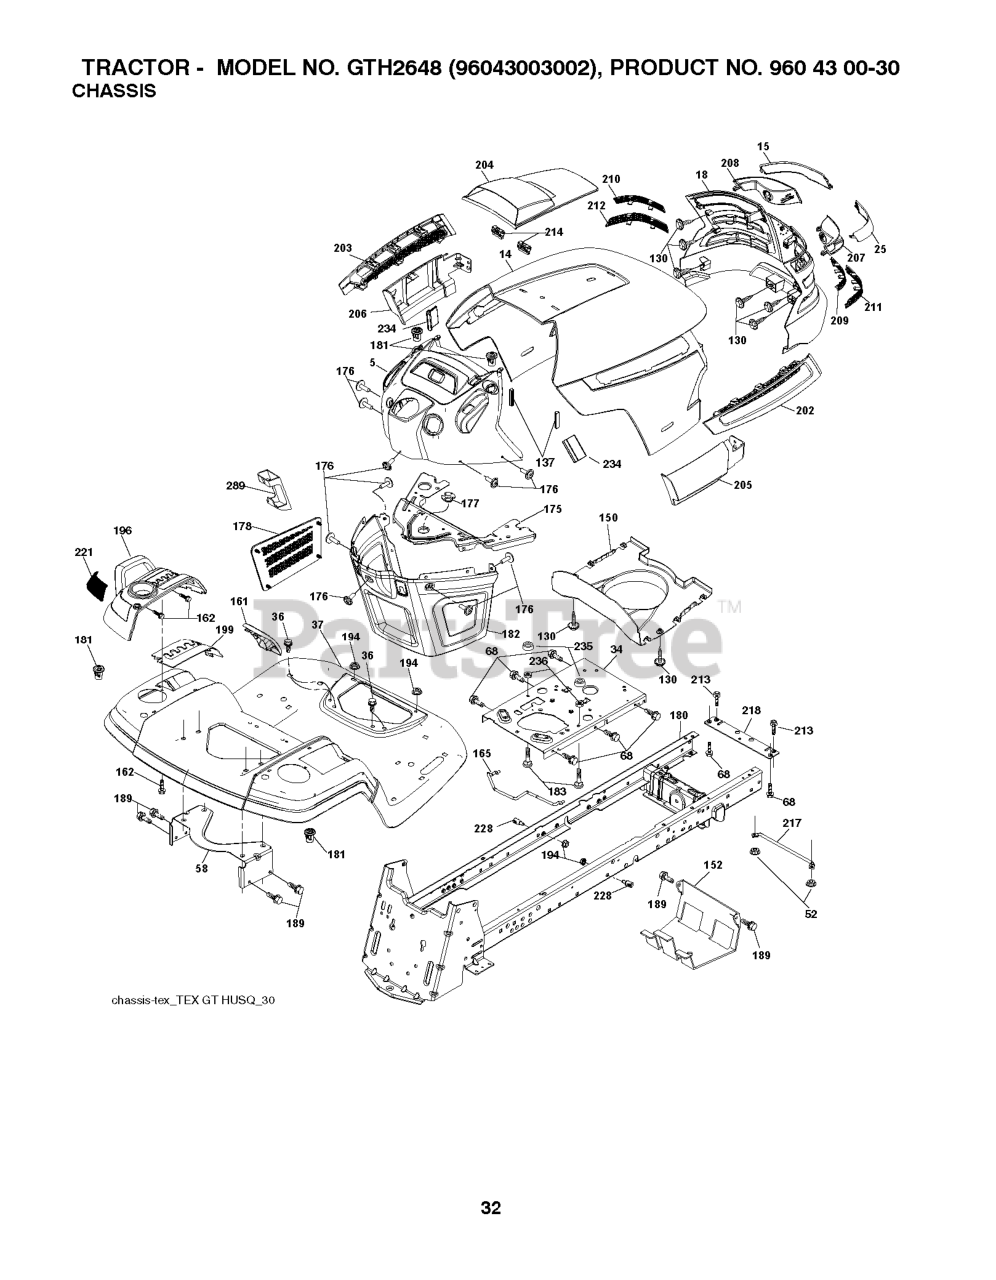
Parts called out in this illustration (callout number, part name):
5	DASH.ASM.HUSQ.GT.E.RECT.W/CK
14	HOOD
15	LENS.LH.TEX.GT.HUSQ.CL
18	GRILL.ASM.HUSQ.TG/CRD.W/TRIM
25	LENS.RH.TEX.GT.HUSQ.CL
34	PLATE.ENGINE.WELDED.CHASSIS
36	SCREW 5/16"
37	FENDER.PNT.TX.GT.CH/FW.ORANGE
52	LOCKNUT
58	BRKT.SUPPORT.FNDR/TANK
68	Screw 5/16-18 x 1/2 Hex, Self Tapping 5/16-18 x 1/2
130	SCREW.#10 X 0.750.BOS
137	BUMPER DASH
150	AIR.DUCT.HOOD.TEX.GT.HUSQ
152	SHIELD.BROWNING.W/TEX
161	CONSOLE.FUEL.WINDOW.HU
162	SCREW.HI-LO.CONSOLE
165	SUPPORT.TANK.REAR.W/TEX
175	PLATE.CROSSMEMBER.HUSQ
176	SCREW.#10-24X5/8.RN.QU
177	BUSHING, STEERING
178	CARGO.ASM.NET.TXGT.W/C
180	CHASSIS.GT.SLOPED.DRAWBAR.
181	BUSHING.MNT.FEND.CRGO.
182	DASH.LOWER.COMMON.12V.ADAPTOR
183	BOLT.5/16-18X1-1/4 FULL.THREAD
189	SCREW
194	NUT LOCK HEX FLANGE 5/16-18
196	RP CONSOLE.ASM.DECKLFT.W/
199	PLATE.DECK.LIFT.HUSQVARNA.GT
202	VENT.SIDE.HOOD.HUSQ.RH.GREY
203	VENT.SIDE.HOOD.HUSQ.LH.GRAY
204	VENT.ASM.TORPHD.HUSQGT.LOGO.CL
205	SKIRT.HOOD.SIDE.HUSQ.RH.GREY
206	SKIRT.HOOD.SIDE.HUSQ.LH.GREY
207	BEZEL.RH.TEX.GT.HUSQ
208	BEZEL.LH.TEX.GT.HUSQ
209	INSERT.HEX.GRILL.HUSQ.GREY
210	INSERT.HEX.GRILL.HUSQ.
211	INSERT.HEX.GRILL.HUSQ.
212	INSERT.HEX.GRILL.HUSQ.
213	BOLT
214	CLIP.RETAINER.TINNER.
217	ROD.PIVOT.HOOD
218	X-PIECE.HOOD.STOP.NON/
221	REFLECTOR.LH.TEX GT HU
228	STUD.FASTNER.W/ANTI-ROTATE
234	BUMPER.HOOD.TEX.HUSQVARNA
235	SPACER FENDER
236	NUT.CENTERLOCK.5/16-
289	PLUG.N/CRUISE.COMMON.YT/GT.BLK
